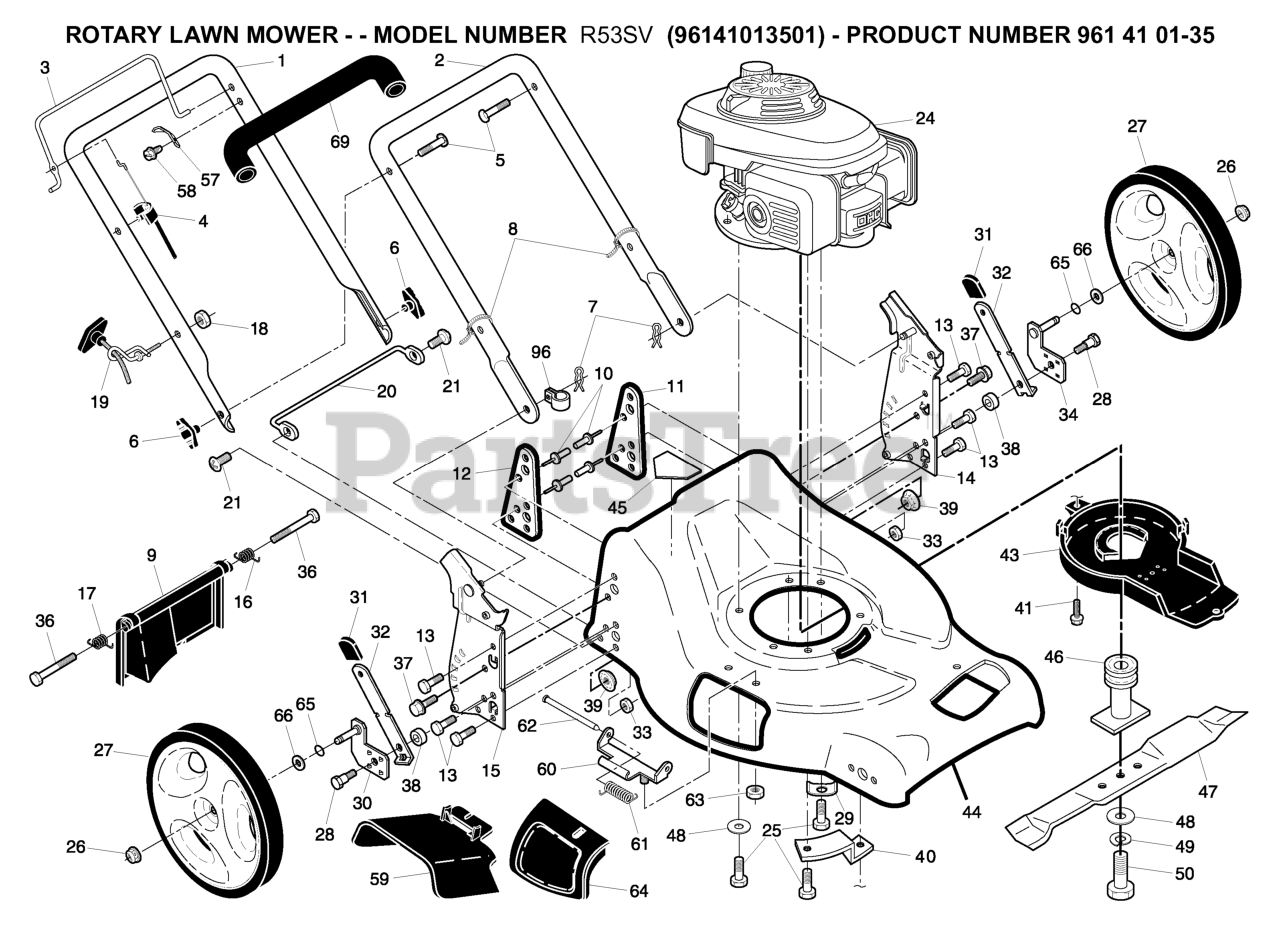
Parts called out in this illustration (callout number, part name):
1	RP HANDLE.ASM.UPPER.W/GRI
2	LOWER HANDLE
3	BAIL.DSTRT.FL.AW.CREAS.ORANGE
4	CABLE.ENGINE BRAKE.MZR
5	BOLT, HANDLE 5/16-18X1.75
6	KNOB, DEFLECTOR
7	HAIRPIN COTTER
8	TIE GUIDE
9	REAR DOOR ASSEMBLY
10	RIVET BLIND
11	SUPPORT BRACKET LH
12	BRACKET.SUPRT.RH.21.FWGD
13	SCREW 14-20 X 5/8
14	BRKT.ASM.HNDL.21FGD.EZ
15	BRKT.ASM.HNDL.21FGD
16	SPRING.REAR.DOOR.EZ.21.LT
17	SPRING.REAR.DOOR.EZ.21.RT
18	NUT
19	RB GUIDE.ROPE.STD.BLK.ZIN WSL
25	BOLT 3/8-16X1-1/8
26	NUT.HEX.FLANGE.3/8-16.LOCKNUT
28	SHOULDER BOLT
29	WASHER.ENGINE.BZP
30	ARM.ASM.AXLE.H/W,RR.BZ
31	SELECTOR KNOB
32	SPRING.SELECTOR.21.FWG.ZINC
33	NUT.71038.31-18.HEX.NYLOCK
34	ARM.ASM.AXLE.H/W.LR.BZ
37	BOLT.FIN.HEX.5/16-18X3/4
38	WASHER.FLAT.34X1.38X22
39	NUT, HEX FLANGE 5/16-18
40	BRACKET
41	SCREW.HEX.WSH
43	DEBRIS SHIELD
44	KIT.HSG.21.FGD.MC.ORG.CE SYM
45	DECAL.INTERNATIONL.CUTFINGER
46	Blade Adapter / Pulley
47	BLADE.21.PUSH
48	WASHER,HARDEN
49	LOCKWASHER
50	SCREW, HEX HD 3/8-24 X 1-3/8
57	BRACKET UPSTOP
59	DEFLECTOR.CLIPPIN.21.FGD
60	BRACKET.ASM.HINGE.21.FWGD.
61	SPRING.TORSION
62	ROD.HINGE.21
63	LOCKNUT.NYLOC.1/4-20
64	DOOR.MULCH.21.REAR.FWGD
65	O-RING..070X.487.NEOPRENE
66	WASHER.FLAT.1/2
69	GRIP.HANDLE.FOAM.WIDE.(1 SIDE)
96	CLIP.CABLE.BLK
